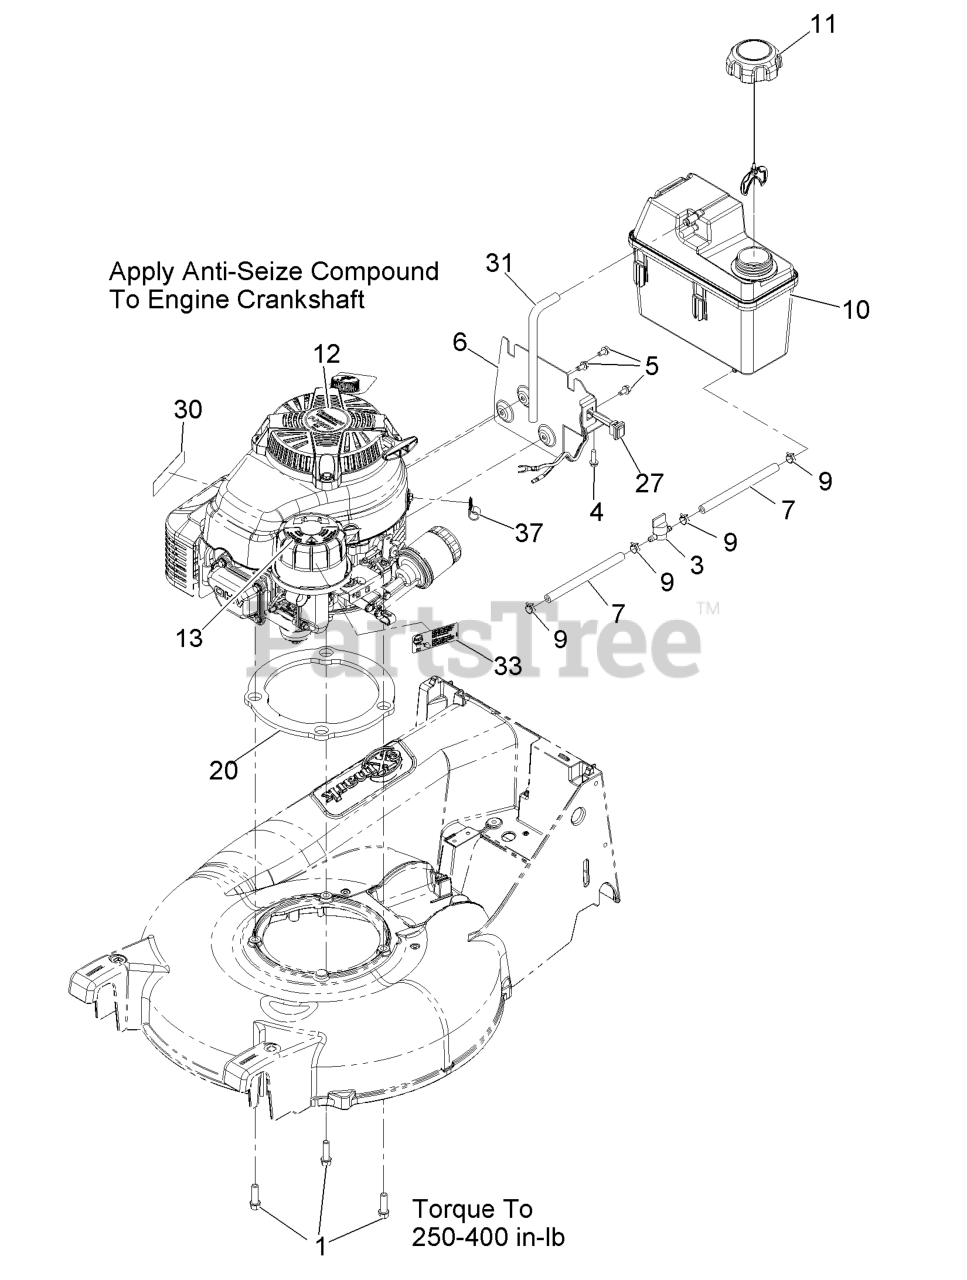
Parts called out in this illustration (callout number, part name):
1	SCREW-TAPTITE
3	VALVE-FUEL
4	SCREW-HWH
5	SCREW-HWH
6	BRACKET,FUEL TANK
7	HOSE-FUEL
9	CLAMP-HOSE
10	TANK-FUEL
20	GASKET,DECK
27	HARNESS,RUN/STOP
30	DECAL-ARRESTER, SPARK
31	HOSE-VENT, CANISTER
33	DECAL, PRIMER
37	CLIP-LOOM
